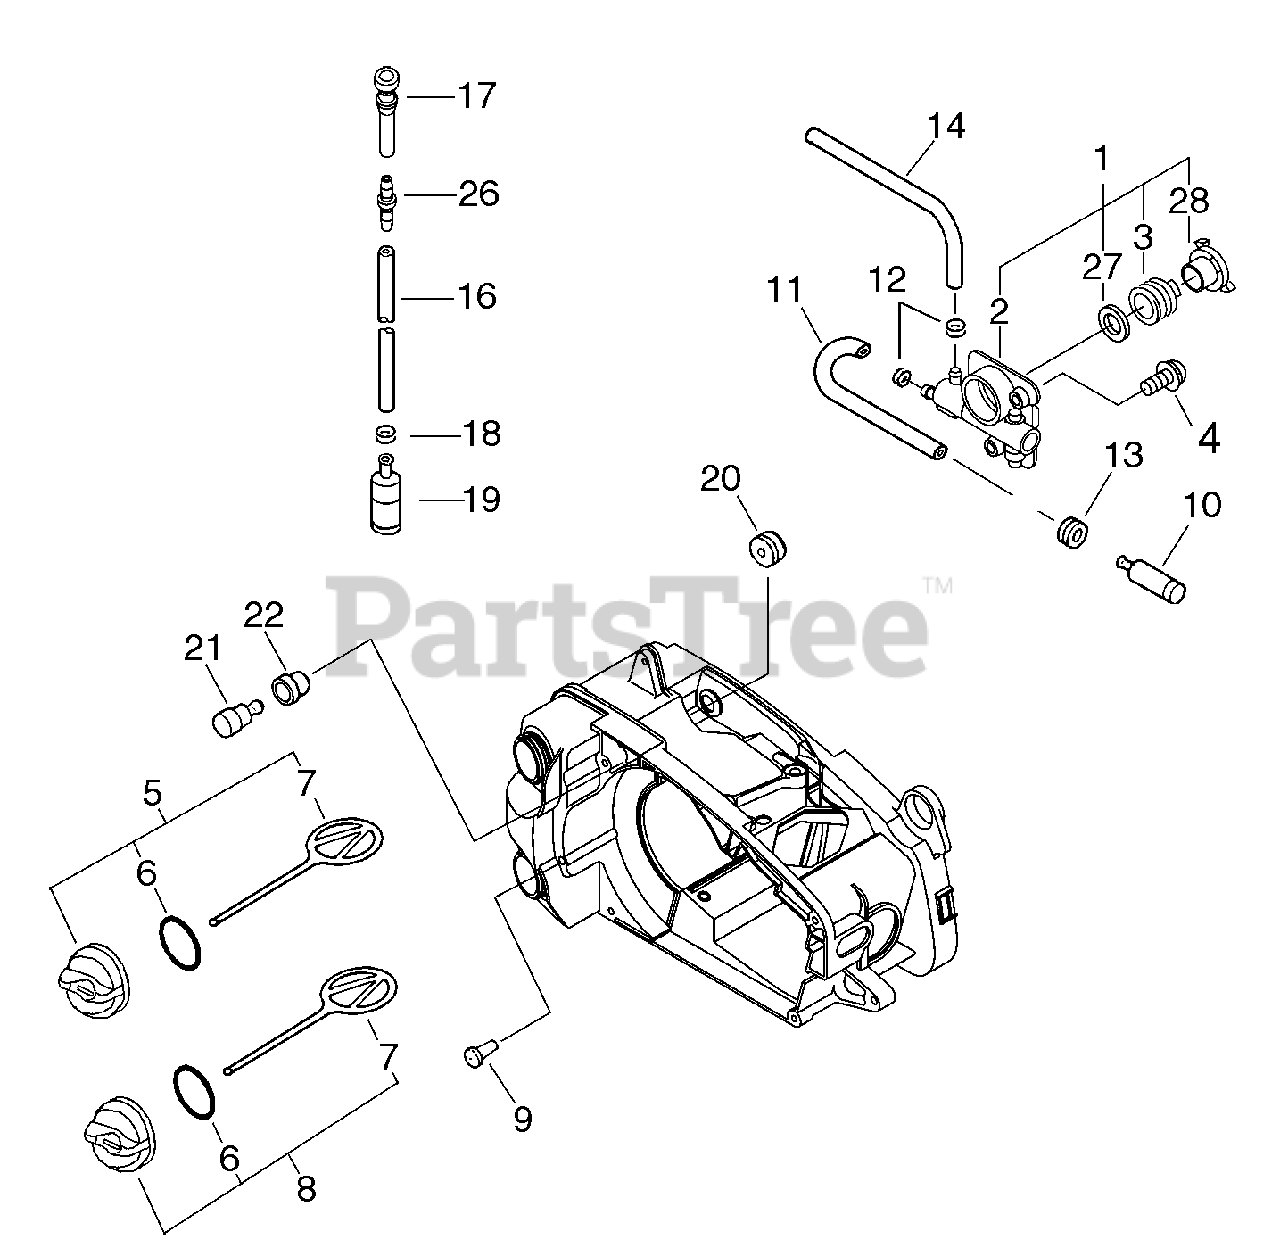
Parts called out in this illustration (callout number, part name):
1	AUTO-OILER KIT
2	AUTO-OILER ASSY
3	GEAR, WORM
4	SCREW 4×12
5	CAP ASSY
6	O-RING 18
7	CONNECTOR, CAP L= 60 MM
8	CAP ASSY - BLACK
9	VENT ASSY
10	FILTER, OIL
11	PIPE 3×6×160
12	CLIP 6.5 MM
13	GROMMET
14	PIPE 3×6×90 MM
16	PIPE, FUEL
17	PIPE, FUEL
18	CLIP 6 MM
19	FILTER, FUEL
20	GROMMET, FUEL
21	VENT ASSY
22	GROMMET, FUEL
26	CONNECTOR, PIPE
27	WASHER 10.5×17.4×1.8
28	COLLAR 10
